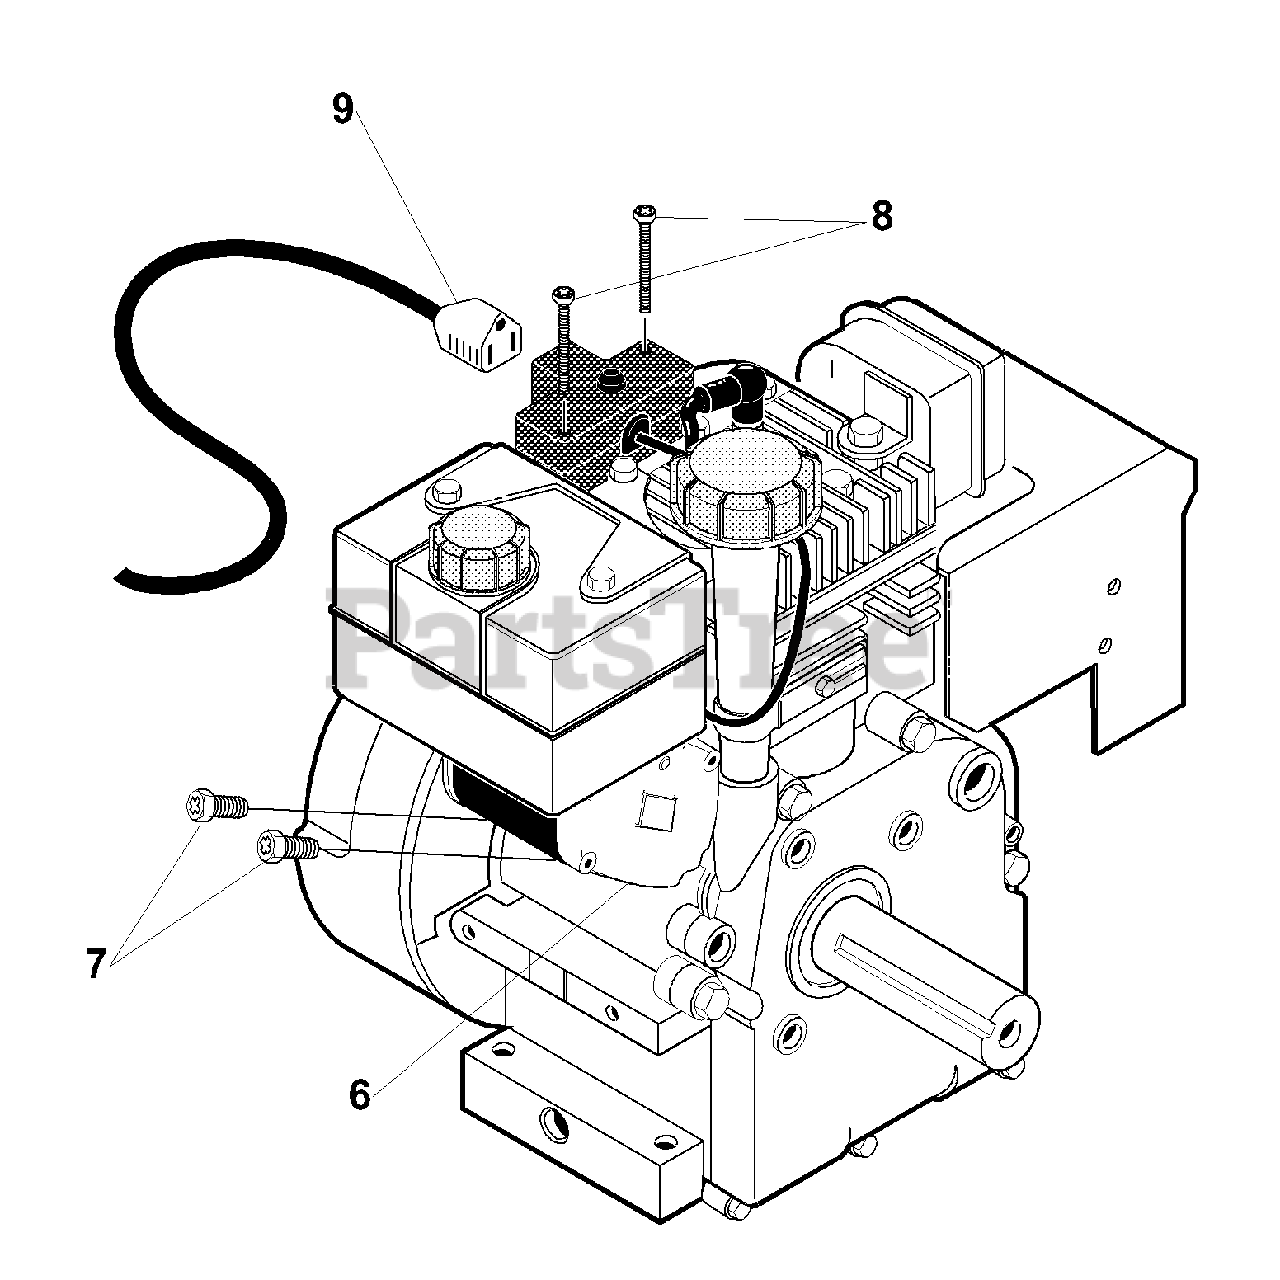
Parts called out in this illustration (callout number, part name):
6	MOTOR, STARTER TEC. 120V
7	SCREW 1/4-20X.50 HWASEMSTOR
8	SCREW #6-32 X 2.50
9	CORD, STARTER MOTOR
